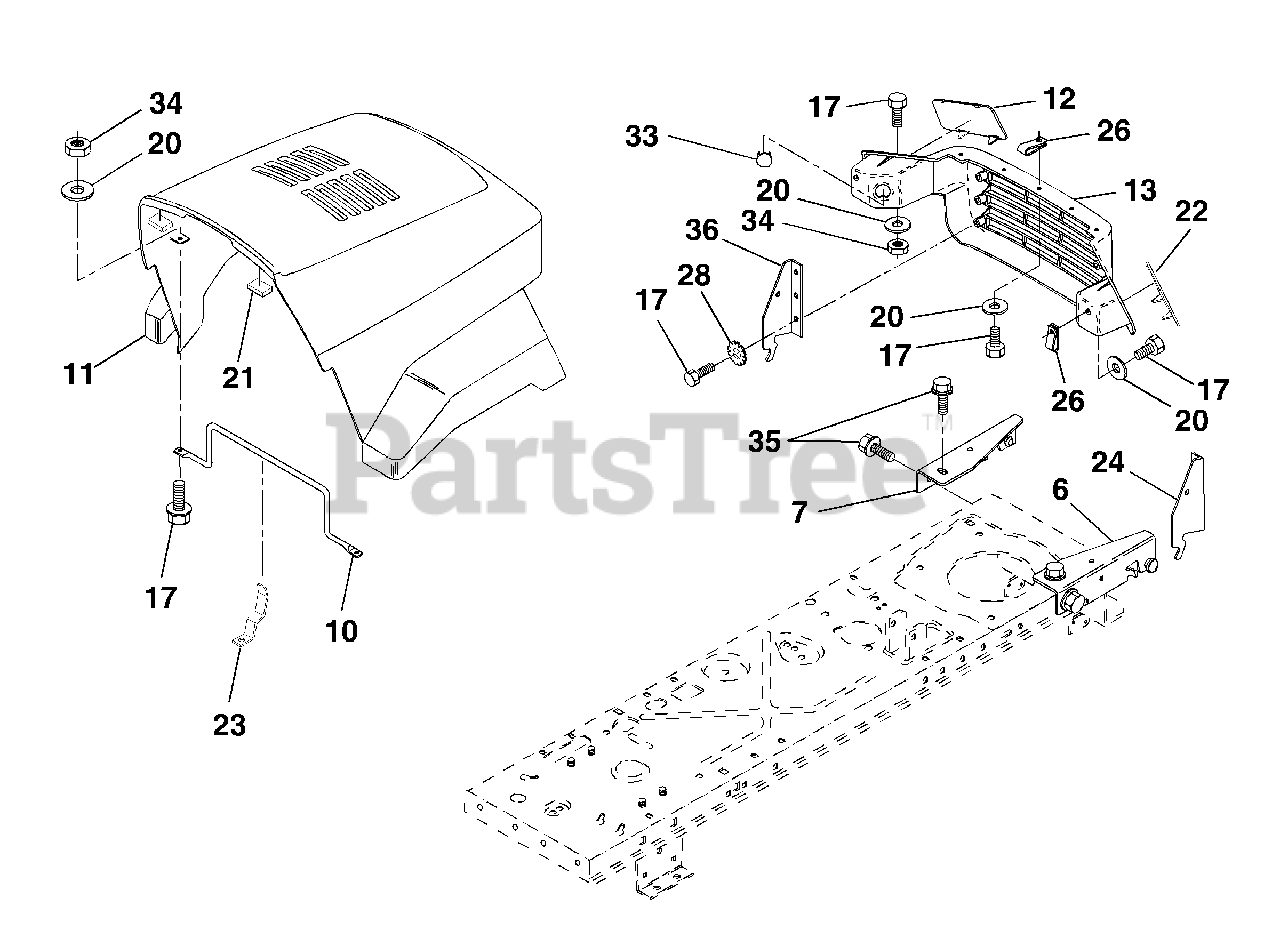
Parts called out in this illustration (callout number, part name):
6	Bracket Asm., Pivot Hood RH
7	Bracket Asm., Pivot Hood LH
10	Brace, Hood
13	Grille
17	Bolt, Fin Hex 1/4-20 x 5/8
20	Washer, Flat 1/4
21	Bumper, Hood
23	Latch, Hood
24	Bracket, Pivot Hood RH
26	Clip, Tinnerman
28	Washer, Lock Ext. Tooth
33	Plug, Socket Light
34	Nut, Fin Hex 1/4-20
35	Screw, Thdrol 5/16-28 x 3/4
36	Bracket, Pivot Hood LH
